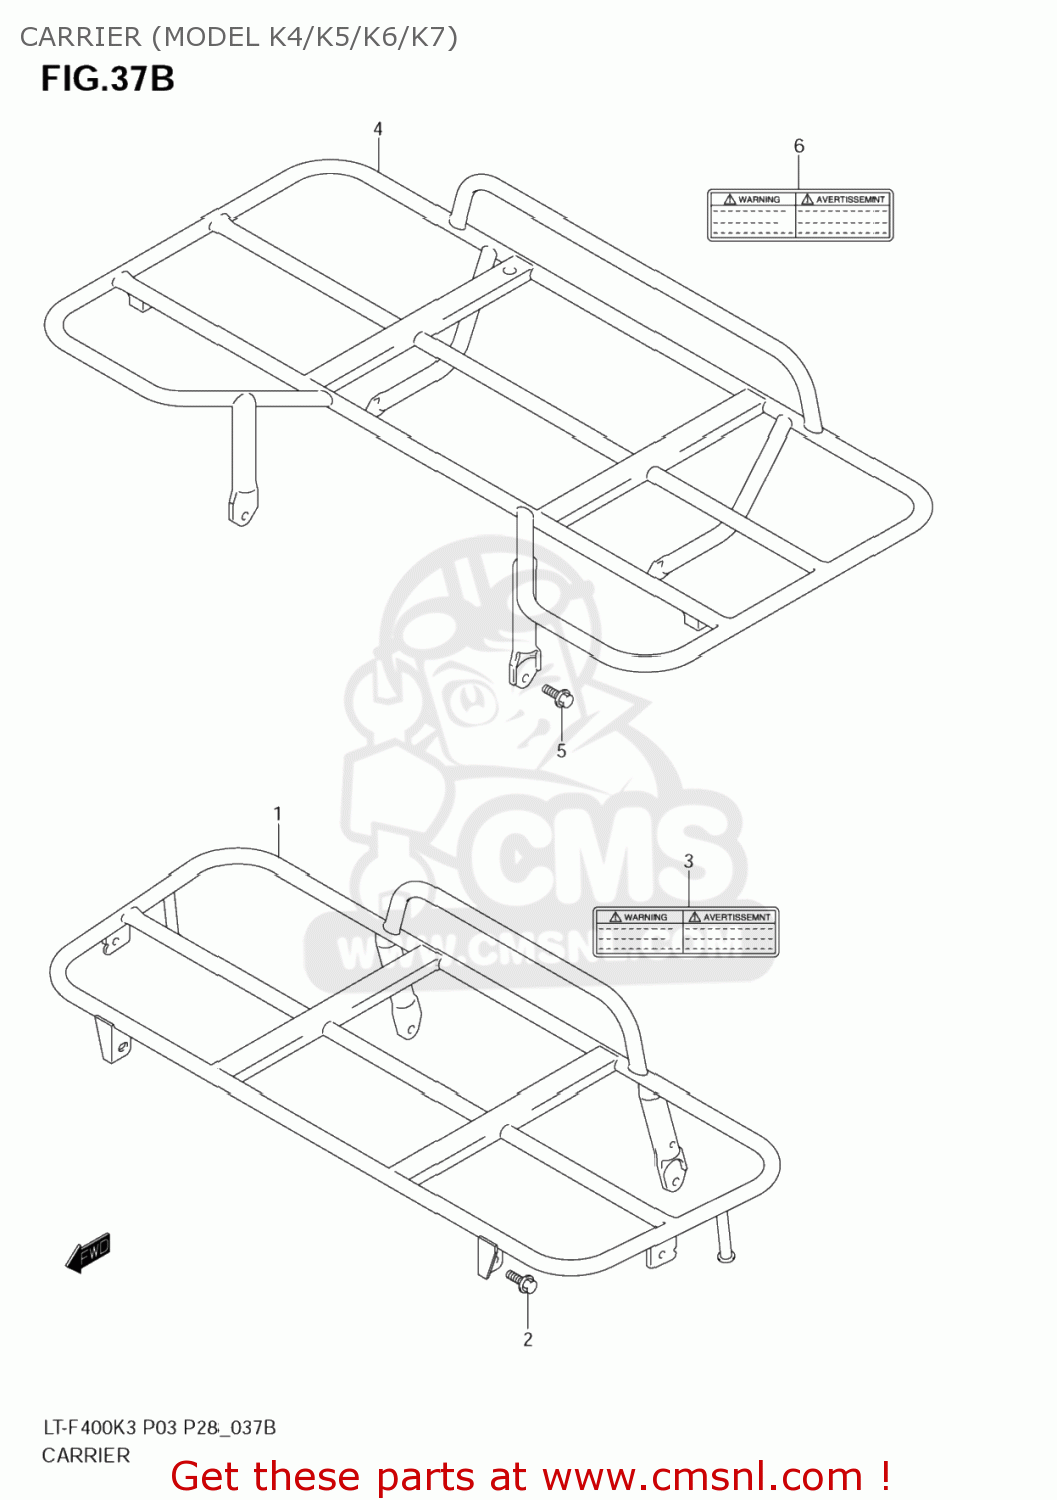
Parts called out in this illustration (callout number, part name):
1	CARRIER,FR
2	BOLT
3	LABEL,FR CARRIER WARNING
4	CARRIER,RR
5	BOLT(8X16)
6	LABEL,RR CARRIER WARNING
